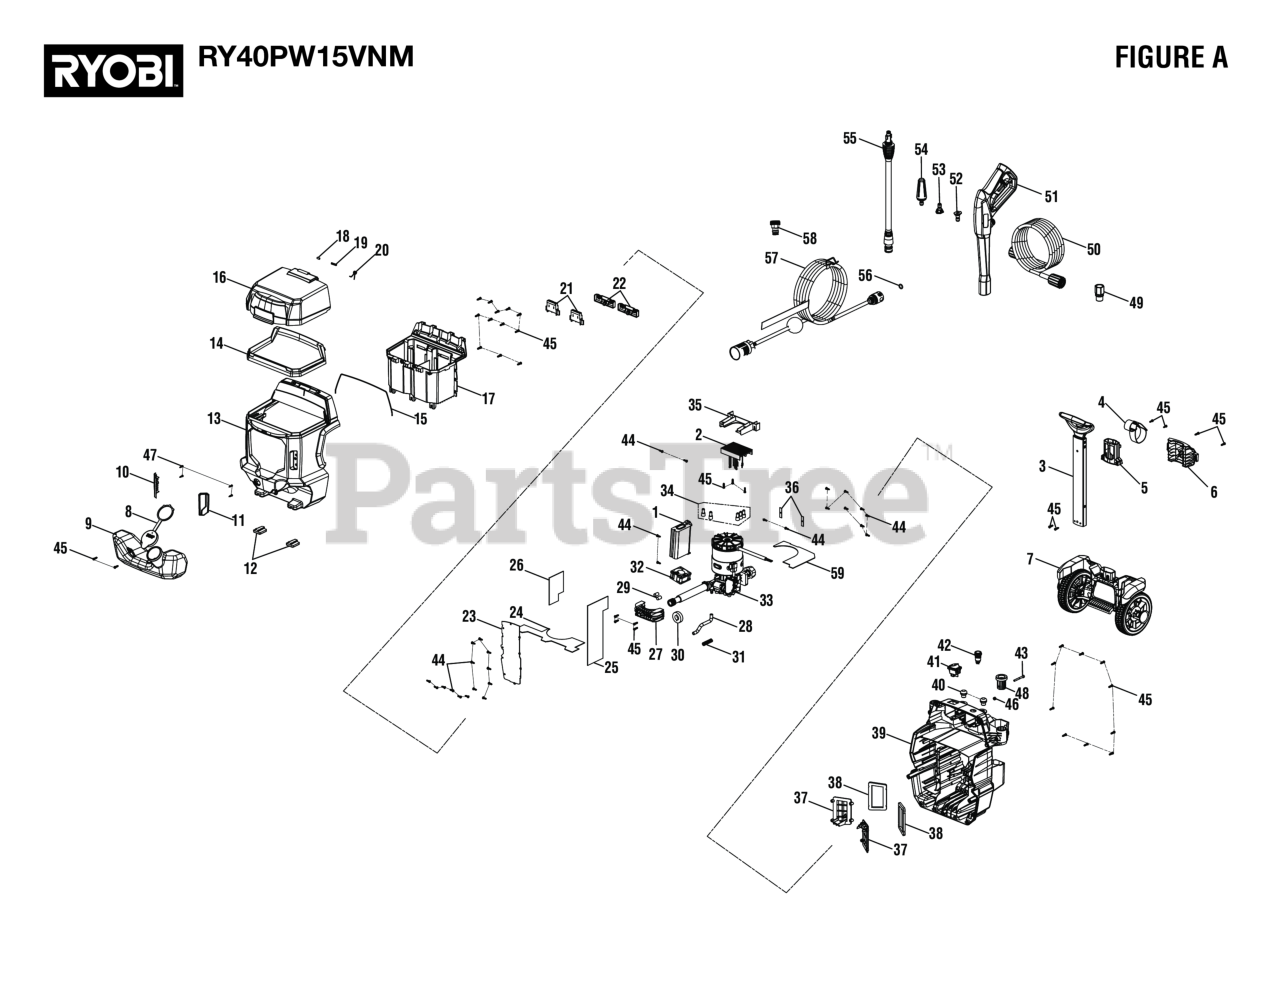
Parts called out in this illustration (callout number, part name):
1	40V DC Controller
2	Control Board Assembly
3	Retractable Handle Assembly
4	Hook and Loop Strap
5	Hose Bracket
6	Holder Cover
7	Wheel Base Assembly (See Fig C)
8	Detergent Tank Cap
9	Soap Tank
10	Mount Cover (Left)
11	Mount Cover (Right)
12	Rubber Foot
13	Front Housing
14	Battery Cover Rubber Seal
15	Front Housing Rubber Seal
16	Battery Cover
17	Battery Tray
18	Battery Door Axle
19	Compression Spring
20	Battery Cover Spring
21	Battery Holder Assembly (See Fig B)
22	Battery Cover Connector
23	Air Way Cover
24	Air Front Sheet
25	Water Block Sheet (Left)
26	Water Block Sheet (Right)
27	Pump Bracket
28	Siphon Tube
29	Shock Absorbing Bushing
30	Outlet Tube Cover Foam
31	Detergent Tank Spring (Compression Spring
32	Control Board Cooling Fan
33	Motor and Pump Assembly
34	Close-End Connector
35	Control Board Bracket
36	Metal Plate
37	Corner Cover
38	Cover Sealing Foam
39	Rear Housing
40	Nozzle Grommet
41	Power Switch
42	Boost Button
43	Bolt (M5 x 42 mm)
44	SCREW, ST3.5X12, PAN HEAD
45	Screw (M4.2 x 15 mm, Phillips Hd. S.T.)
46	Lock Nut (M5 x 0.8 mm)
47	Screw (M2.9 x 14 mm, Pan Hd.)
48	Primer Post Rubber Seal
49	Priming In-Line Accessory
50	25 ft. Hose
51	Trigger Handle
52	15 Deg Nozzle
53	Soap Nozzle (Blue)
54	Turbo Nozzle
55	Spray Wand Assembly
56	O-Ring (ID11.3 x CS2.5)
57	Suction Hose w/Swivel Connector
58	Inlet Connector
59	Air-Separation Sheet
